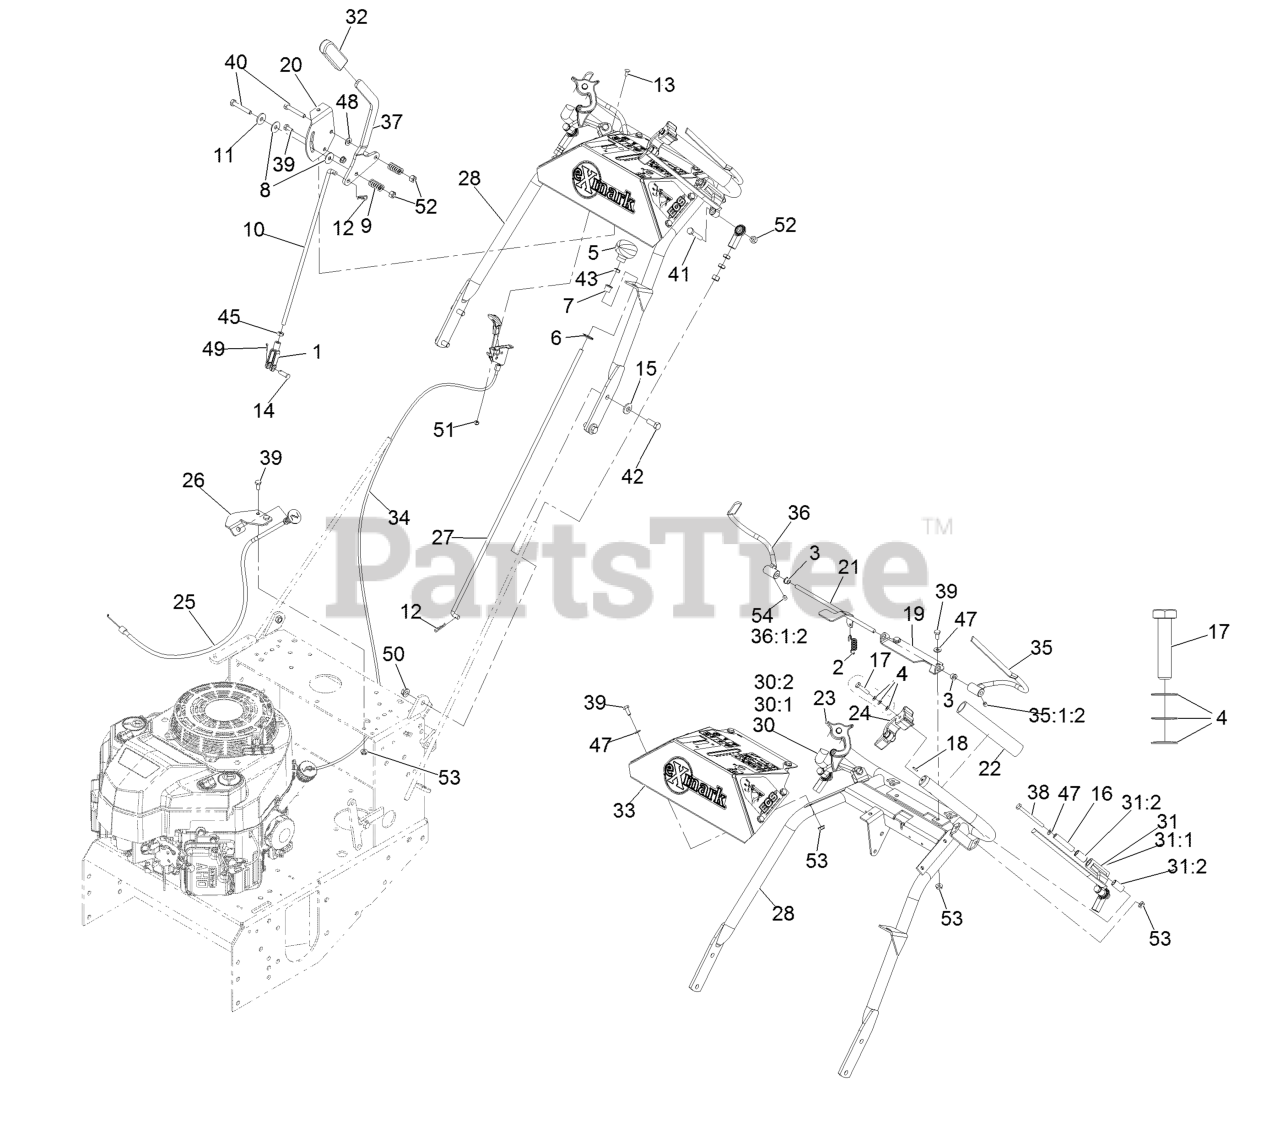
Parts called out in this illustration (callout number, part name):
1	Yoke-Adjustable
2	Spring-Extension
3	Bushing-Nylon
4	Washer-Spring Disc 1/4
5	Knob-Push / Pull
6	Nut-Push 1/2
7	Bearing-Nylon
8	Washer-Friction
9	Spring-Compression
10	Rod-Control, Speed
11	Washer-Friction Disc
12	Hairpin-Cotter
13	Bolt-Carriage #10-24 X 1/2
14	Pin-Clevis 5/16 X 1 49/64
15	Washer-Spring Disc 3/8
16	Bushing-Lever, Drive
17	Screw-HH 1/4-20 X 1 1/8 W/Nylon
18	Pin-Spring
19	Bracket, Opc Axle
20	Bracket,Shifter Slide
21	Rod Weldment, OPC
22	Grip-Bar, Handle
23	Thumb Latch Asm RH
24	Thumb Latch Asm LH
25	Cable-Choke
26	Bracket-Cable, Choke
27	Link, Blade Engagement
28	Handle Wld, Upper Ecs
30	Asm, Drive Lever RH
30:1	Wld,RH Drive Lever
30:2	Bushing, Sleeve
31	Asm, Drive Lever LH
31:1	Wld,LH Drive Lever
31:2	Bushing, Sleeve
32	Grip-Handle, Steering
33	Asm, Console W/Decals
34	Control, Throttle
35	Wld,LH OPC Lever
35:1:2	Setscrew-5/16-24 X 5/16
36	Wld,RH OPC Lever
36:1:2	Setscrew-5/16-24 X 5/16
37	Lever-Shift
38	Screw-HH 1/4-20 X 2 3/4
39	Screw-HH 1/4-20 X 5/8
40	Screw-HH 5/16-18 X 2
41	Screw-HH 5/16-18 X 1 3/4
42	Screw-HH 3/8-16 X 1
43	Nut-Jam 5/16-18
45	Nut-Jam 5/16-24
47	Washer-1/4 SAE
48	Washer-5/16 SAE
49	Pin-Cotter 3/32 X 1/2
50	Nut-Whizlock 3/8-16
51	Nut-Nyloc #10-24
52	Nut-Nyloc 5/16-18
53	Nut-Whizlock 1/4-20
54	Setscrew-5/16-24 X 5/16
